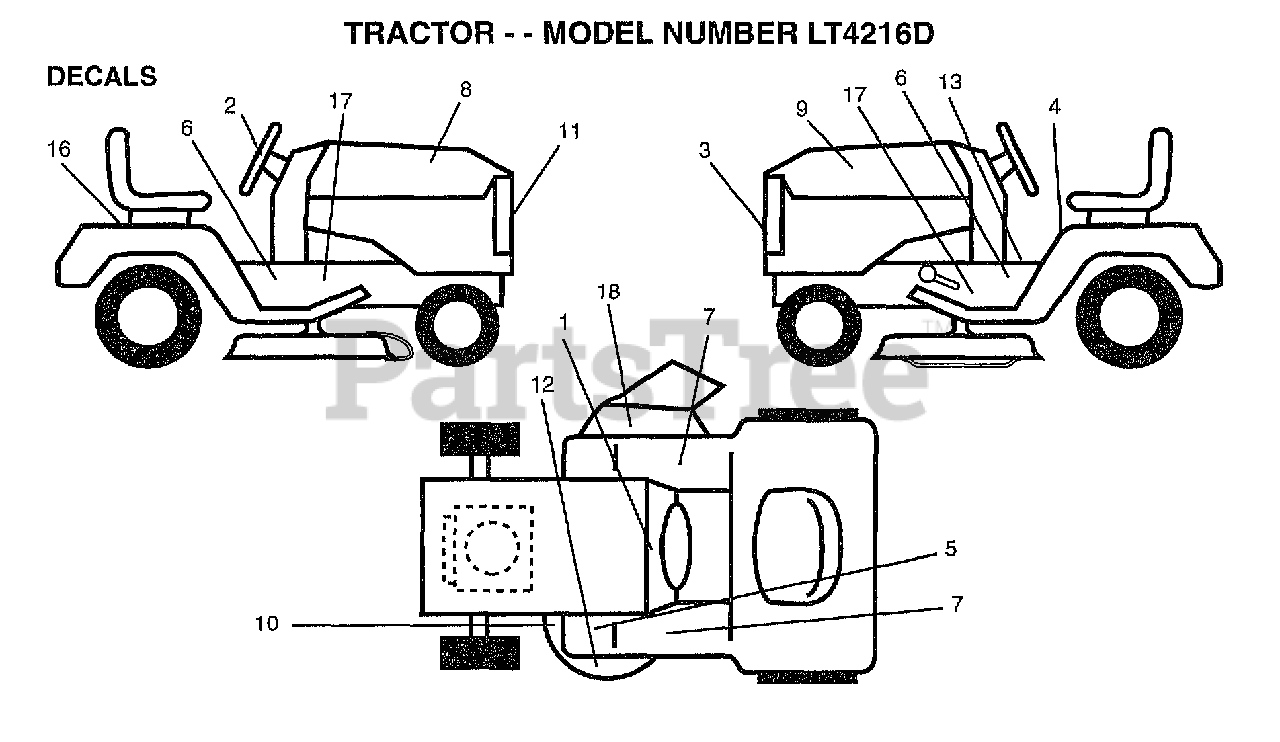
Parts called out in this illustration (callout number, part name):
1	DECAL INST OP DAS
2	DECAL.INST.WHL.ST
3	DECAL LOGO GRILLE
4	DECAL CAUT FEND
5	DECAL CLUT/BRAKE
6	DECAL CHASSIS KGR
7	FOOTREST PAD
8	DECAL.HD.RH.KGRO
9	DECAL.HOOD.LH.KGR
10	DECAL
11	DECAL.GRILLE.KGRO
12	DECAL DECK MULCH
13	DECAL BRAK PARK
16	DECAL FEND QUICK
18	DECAL DANGER CT/F
